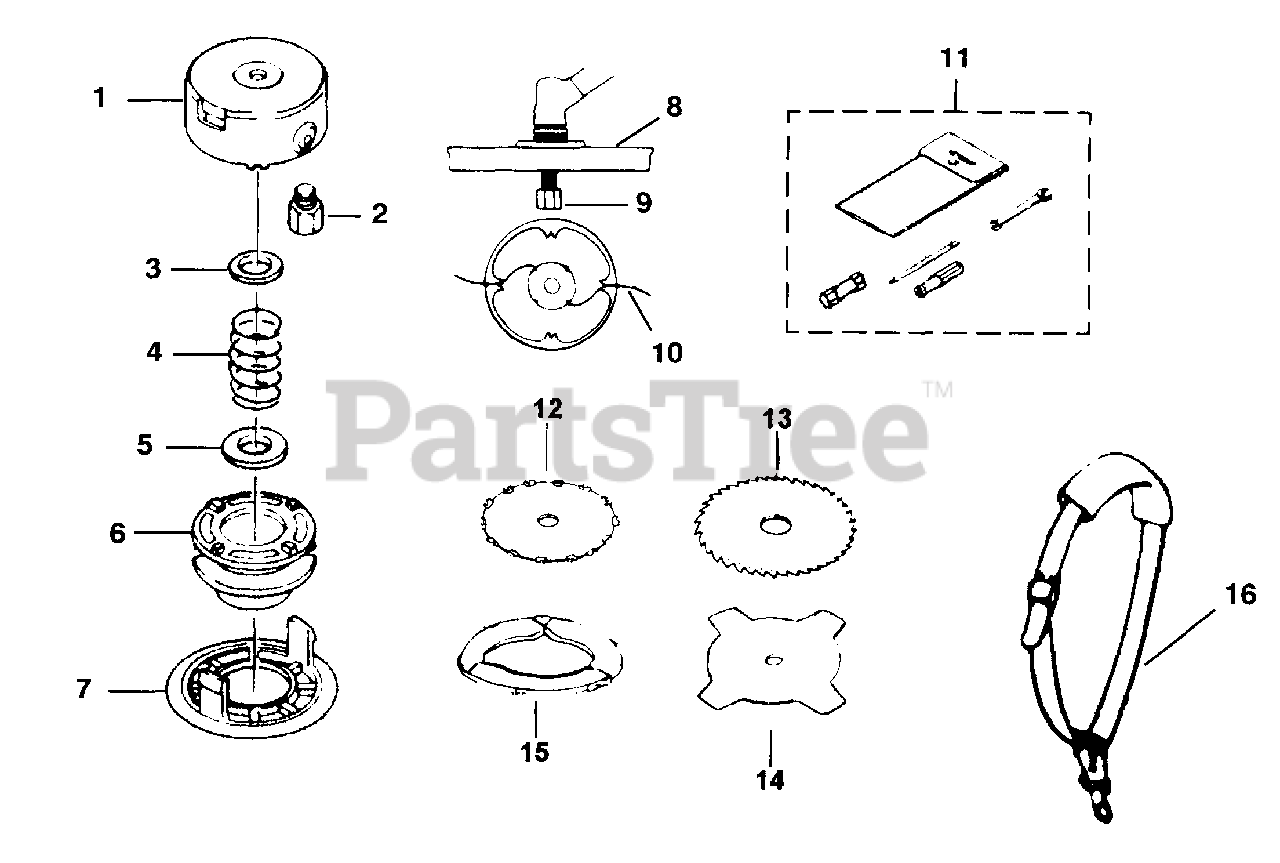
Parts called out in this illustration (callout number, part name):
1	HEAD BODY
2	ARBOR BOLT
3	SPRING PLATE
4	SPRING
5	SPRING PLATE
6	SPOOL
8	FIXED LINE HEAD ASSY (OPT.)
9	ARBOR BOLT
10	GREEN LINE .080 X 20ft.
12	8" XRT BLADE (OPT.)
13	8" SAW BLADE (OPT.)
14	8" QUAD BLADE (OPT.)
15	BLADE COVER (OPT.)
16	HARNESS (OPT)
